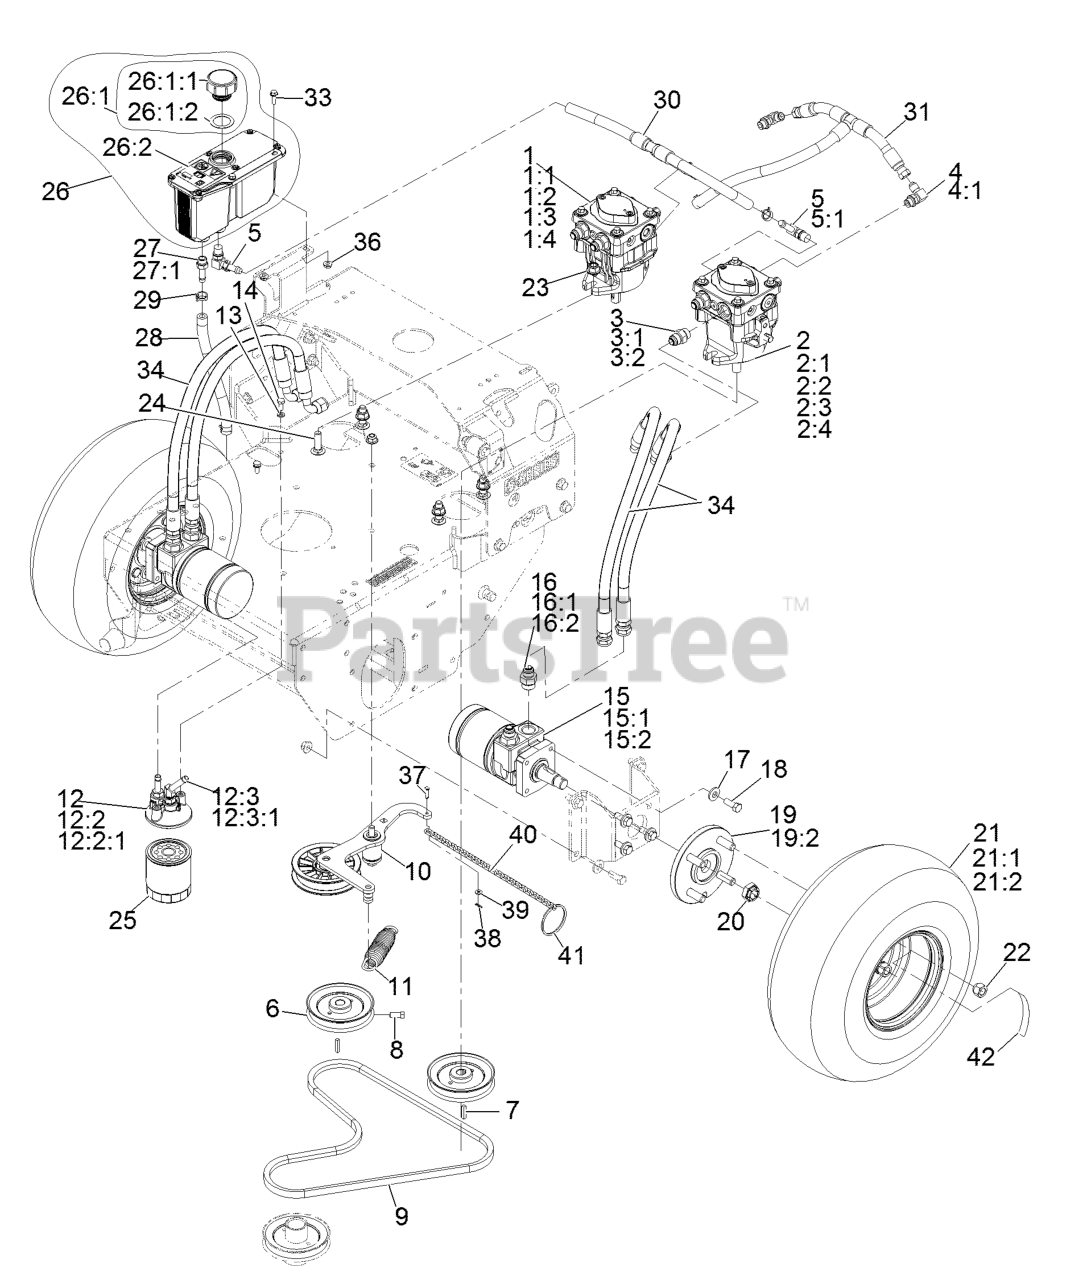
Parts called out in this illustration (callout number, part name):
1	RH HYD PUMP ASM
1:1	INPUT SHAFT KIT
1:2	BEARING-THRUST
1:3	CYLINDER BLOCK KIT
1:4	SEAL OVERHAUL KIT
2	LH HYD PUMP ASM
2:1	INPUT SHAFT KIT
2:2	BEARING-THRUST
2:3	CYLINDER BLOCK KIT
2:4	SEAL OVERHAUL KIT
3	FITTING-STRAIGHT
4	FITTING-ELBOW, 90 DEG
5	FITTING-ELBOW, 90
5:1	O-RING
6	SHEAVE ASM
8	SCREW-SET, SQH
9	BELT
10	ASM, PUMP IDLER
11	SPRING-EXTENSION
12	ASM, FILTER HEAD
12:2	ADAPTER-STRAIGHT
12:2:1	O-RING
12:3	FITTING-BARBED, 45 DEG
12:3:1	O-RING
13	WASHER-LOCK
14	SCREW-HH
15	HYD MOTOR ASM
15:1	SEAL KIT
15:2	BEARING AND SEAL KIT
16	FITTING-STRAIGHT
16:1	O-RING
17	WASHER-BELLEVILLE
18	SCREW-HH
19	WHEEL HUB ASM
19:2	STUD-WHEEL
20	NUT-LOCK
21	WHEEL AND TIRE ASM
21:1	TIRE-TURFMASTER
21:2	RIM-WHEEL
22	NUT-LUG
23	NUT-HF, NI
24	SCREW-HH
25	FILTER-25 MICRON, BI-DIRE
26:1	Reservoir-HYD
26:1:1	Cap-Reservoir, HYD
26:1:2	GASKET-CAP
26:2	DECAL-WARNING
27	ADAPTER-STRAIGHT
27:1	O-RING
28	HOSE-CHARGE
29	CLAMP-HOSE
30	HOSE-CASE DRAIN
31	HOSE-CHARGE
33	SCREW-HWH
34	HYD HOSE ASM
37	PIN-CLEVIS
38	PIN-HAIR
39	WASHER-PLAIN
40	CHAIN-LINK, TWIST
41	RING-SPLIT
42	DECAL-TORQUE WHEEL LUG-HU
